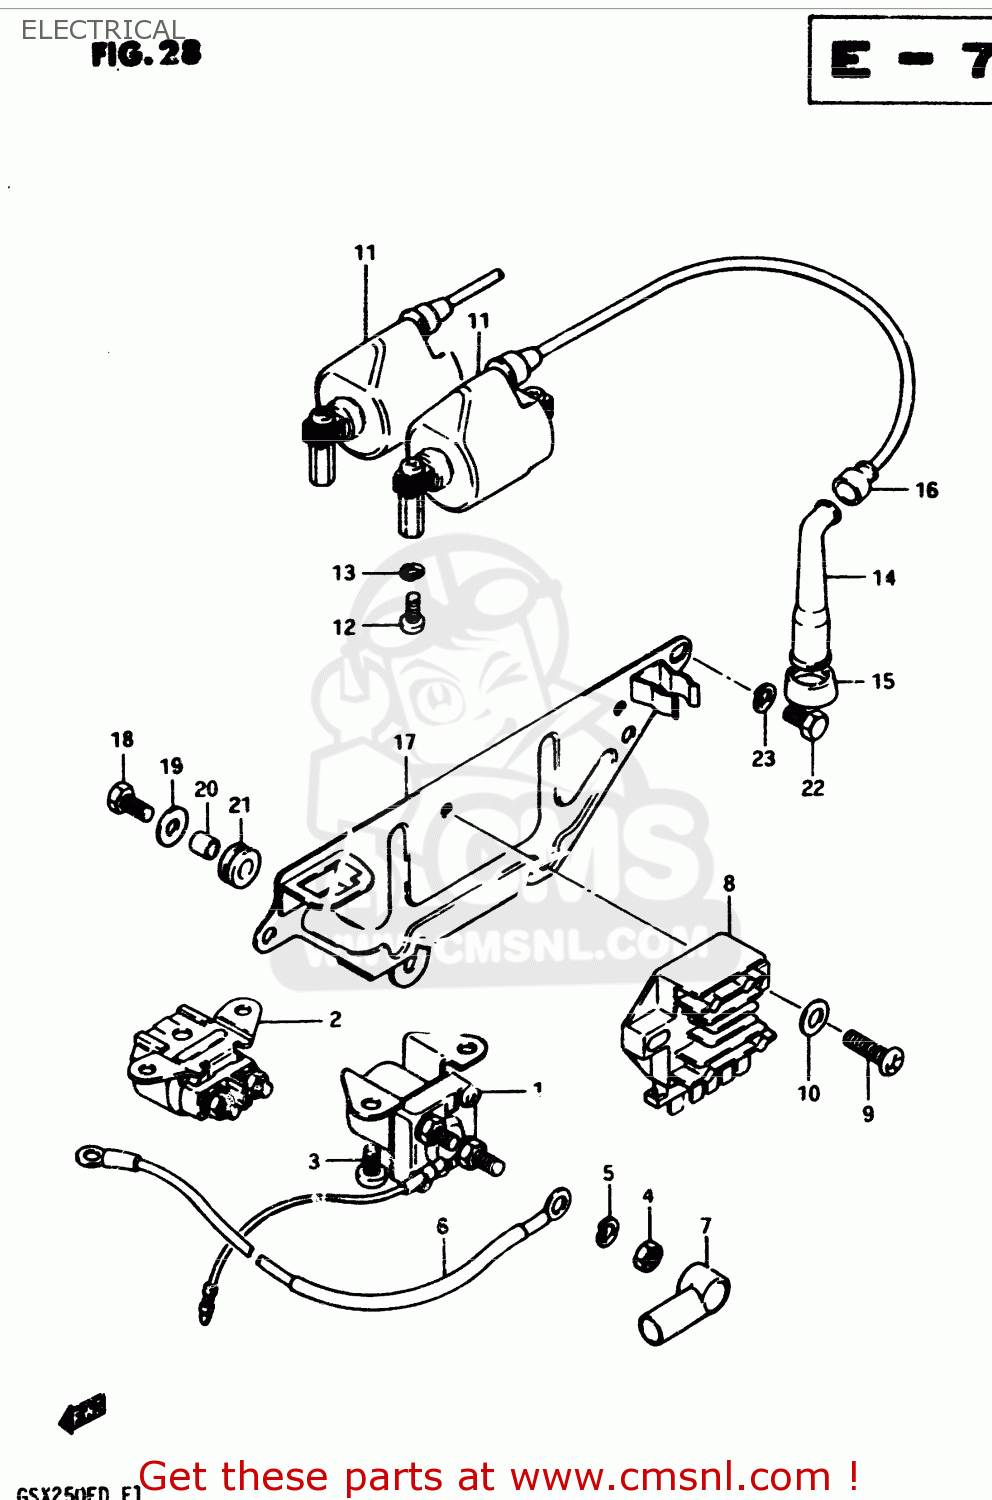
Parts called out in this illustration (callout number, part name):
1	RELAY ASSY,STARTING MOTOR
2	RELAY ASSEMBLY,STARTING MOTOR
3	SCREW
4	NUT 6MM
5	LOCK WASHER
6	CORD,BATTERY MINUS
7	CAP,STARTER RELAY
8	RECTIFIER ASSEMBLY
9	SCREW
10	WASHER
11	COIL ASSEMBLY,IGNITION
12	SCREW
13	LOCK WASHER
14	CAP ASSY,SPARK PLUG
15	SEAL,SPARK PLUG
16	SEAL,SPARK PLU
17	HOLDER COMP,ELECTRONIC PARTS
18	BOLT
19	WASHER
20	SPACER (6.1X8X9.5)
21	CUSHION
22	BOLT
23	LOCK WASHER
